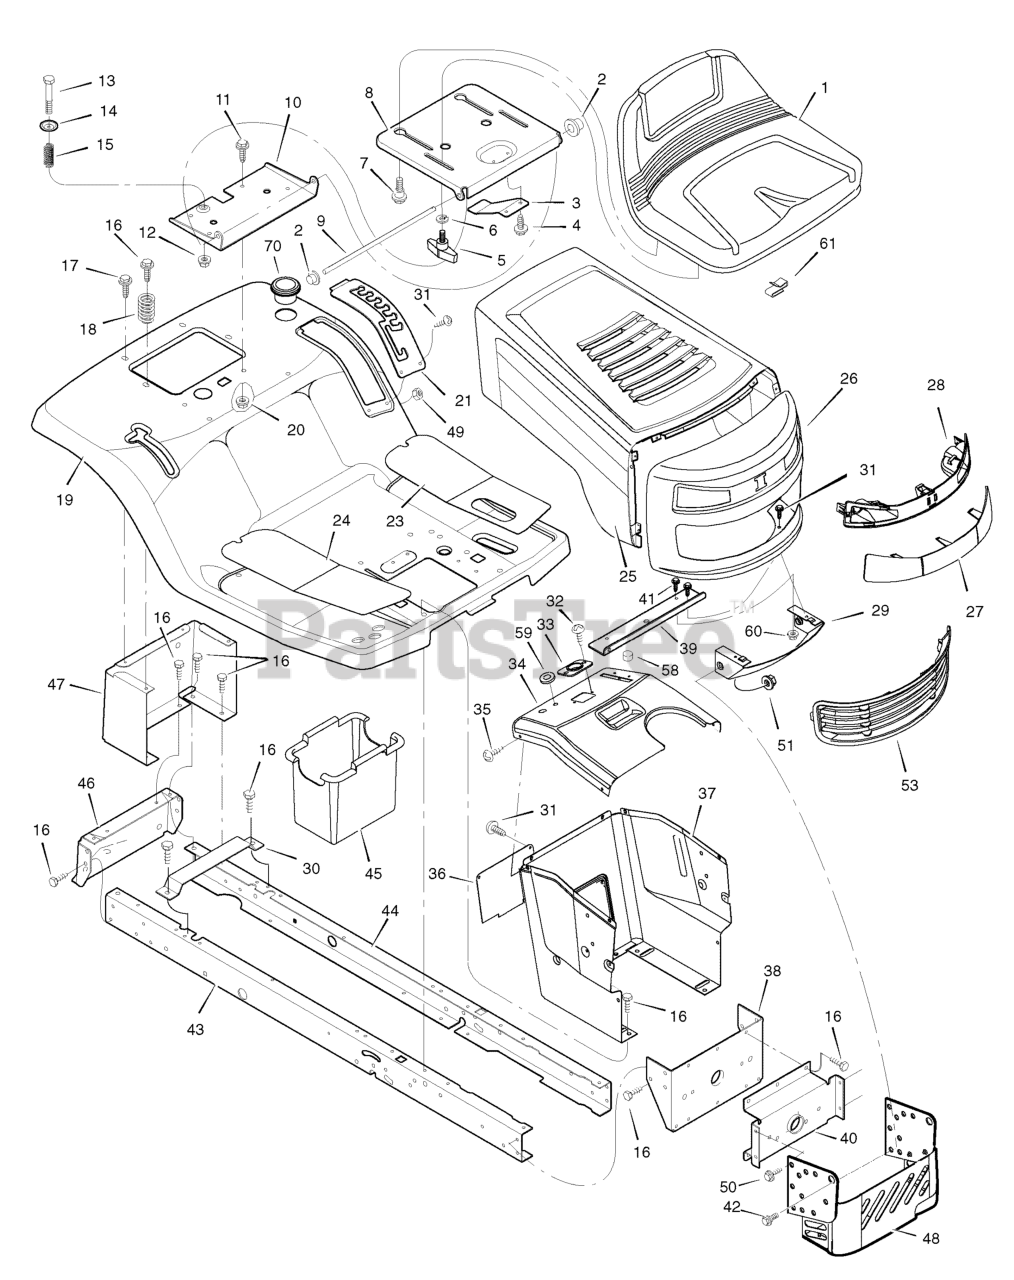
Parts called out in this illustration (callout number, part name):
1	SEAT
2	CAP, Push On
5	BOLT, Wing
6	WASHER
7	BOLT, Shoulder
8	SUPPORT, Seat
9	ROD, Pivot
10	BRACKET, Pivot
11	BOLT
13	BOLT, Shoulder
19	DECK, Seat
20	NUT
21	PLATE, Lift
23	MAT, Left
24	MAT, Right
25	HOOD, WM1
28	HOUSING, Headlamp
29	BRACKET, Lower Pivot
30	SUPPORT, Battery
33	BEARING, Steering
36	PANEL, Access
37	SUPPORT, Dash
38	BRACKET, Rear Hanger
39	BRACKET, Support
40	AXLE, Hanger
42	BOLT, Shoulder
43	FRAME, Right
44	FRAME, Left
45	CONTAINER, Battery
46	PLATE, Hitch
47	PANEL, Rear
48	SHIELD, Heat
53	INSERT, Center Grille
59	GROMMET, Parking Brake
60	NUT
61	S-CLIP, Black
70	HOLDER, Beverage
